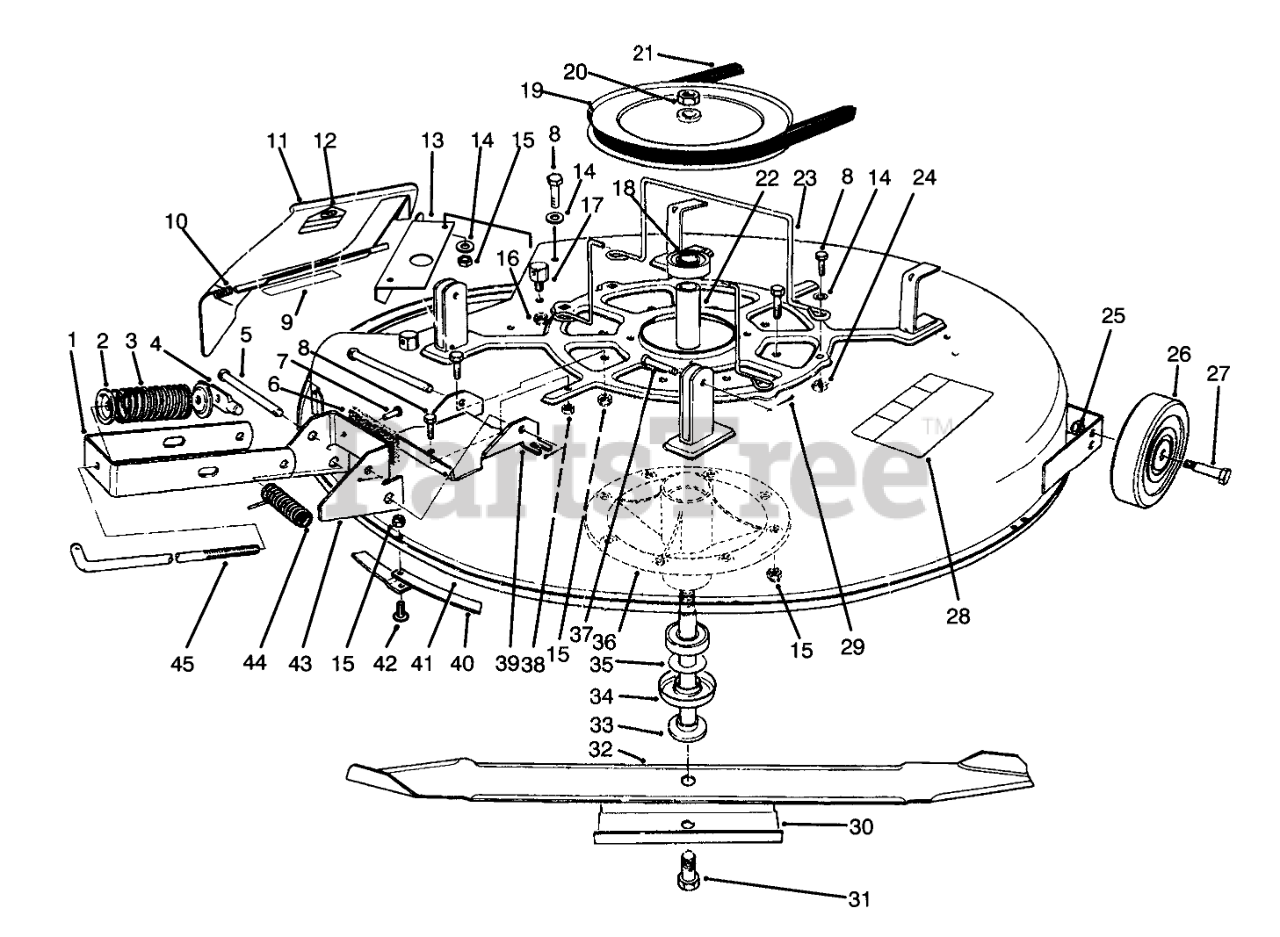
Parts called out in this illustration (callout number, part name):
1	Bracket-Engagement
2	RETAINER-SPR. TOP
3	SPRING-COMPRESSION
4	SHAFT-DECK ADJ.
5	PIN-CLEVIS
6	PAD-BRAKE
7	RIVET .187 X 7/16 BRASS
8	SCREW-HH
9	DECAL-DANGER, DEFLECTOR
10	SPRING
11	Assembly-Deflector (Incl. Ref. #12)
12	DECAL-DANGER
13	Baffle Deck
14	WASHER-PLAIN
15	NUT-LOCK, NI
16	NUT-LOCK, NI
17	POST-PIVOT
18	BEARING-BALL
19	PULLEY
20	NUT-HEX
21	V-BELT, DECK
22	SPACER-BEARING
23	GUIDE-BELT
24	NUT-RETAINER
25	NUT-LOCK, NI
26	WHEEL-DECK
27	BOLT-WHEEL
28	DECAL-DANGER, THROWN OBJECT
29	PIN-COTTER
30	STIFFENER
31	SCREW-HH
32	Blade
33	SHAFT-SPINDLE
34	SHIELD-BEARING
35	SPACER-HARDNED
36	SPINDLE
37	PIN-CLEVIS
38	NUT-HEX
39	Plate-Deck, Brake Mtg.
40	Ring-Deck
41	Deck-Cutting
42	SCREW-PPH
43	Assembly Brake (Incl. Ref. #6-7)
44	SPRING
45	ROD-ENGAGEMENT
